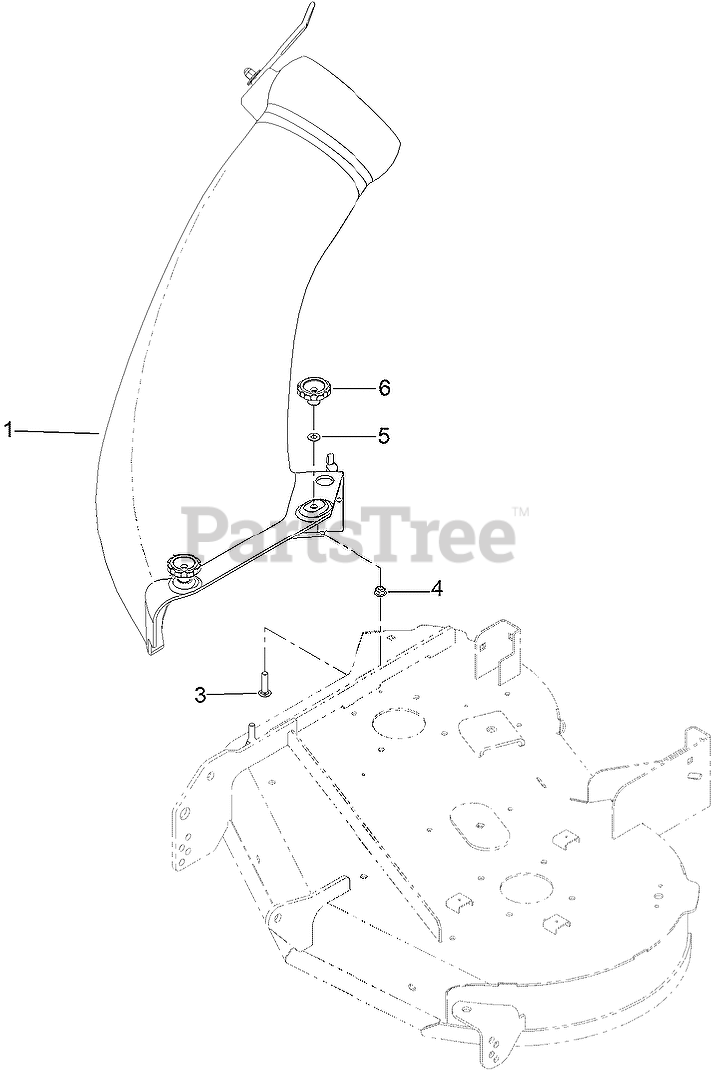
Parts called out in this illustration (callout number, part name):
1	34 INCH CHUTE ASM
3	BOLT-CARRIAGE 5/16-18 X 1 3/8 SHORT NECK
4	NUT-HF, NI
5	WASHER-PLAIN
